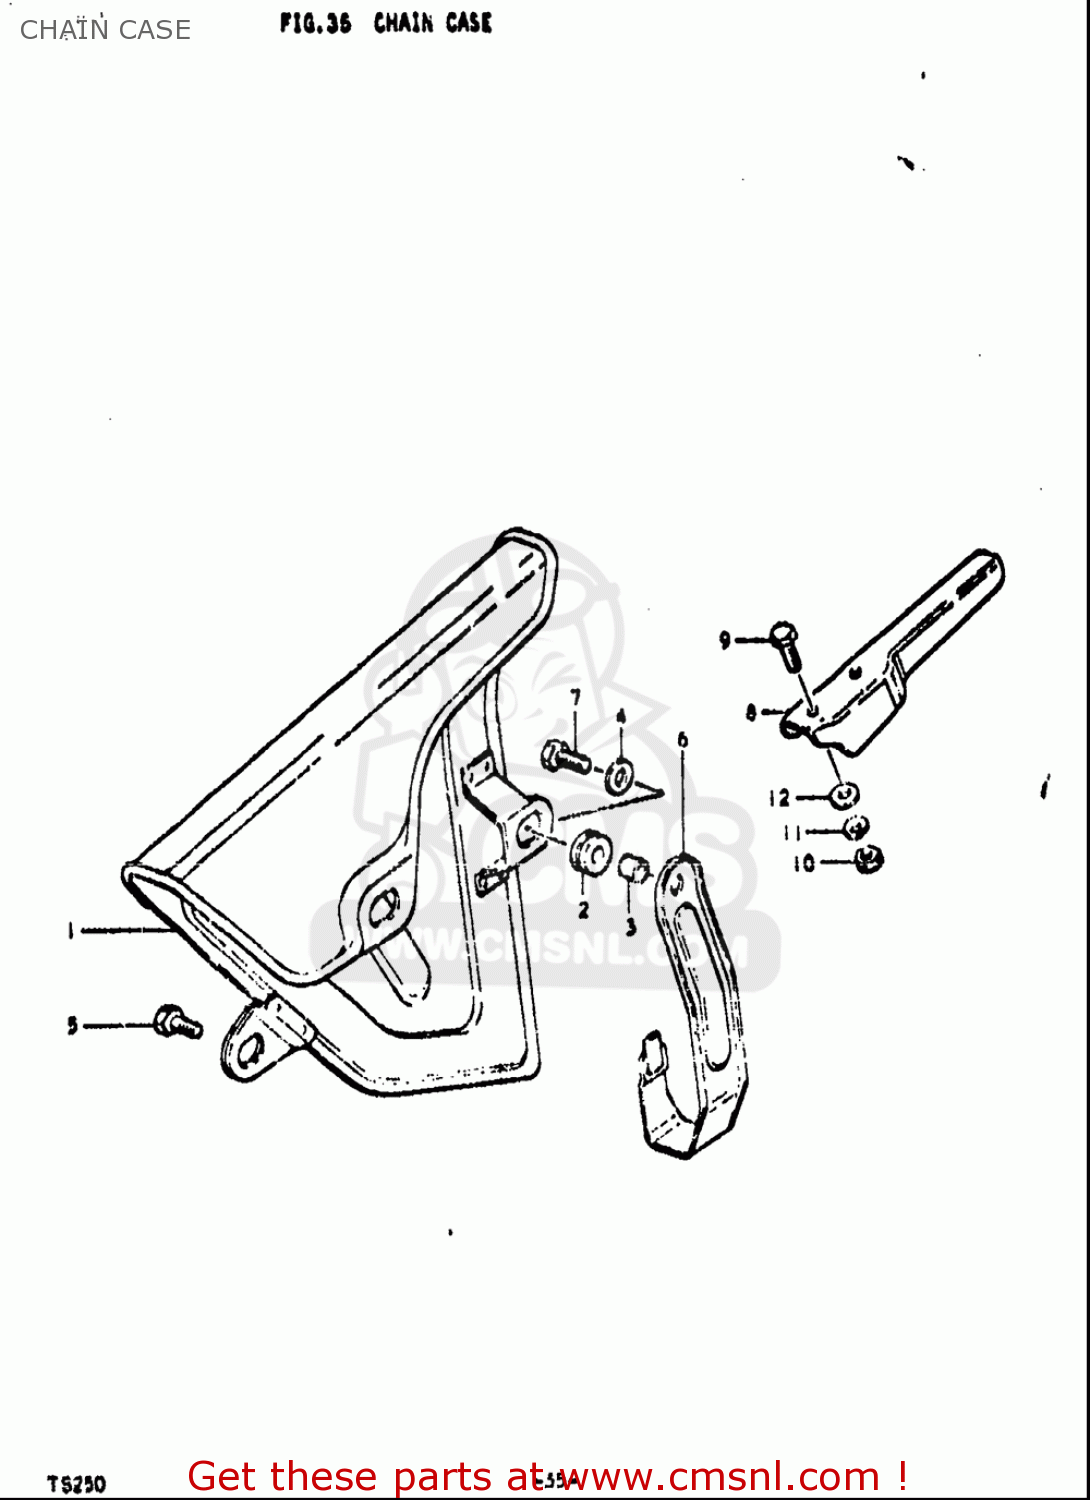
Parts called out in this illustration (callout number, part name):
2	CUSHION
3	SPACER,6.5X9X7
4	WASHER(6.5X20X1.2)
5	BOLT
7	SCREW(6X14)
9	BOLT
10	NUT
11	WASHER,LOCK
12	WASHER
